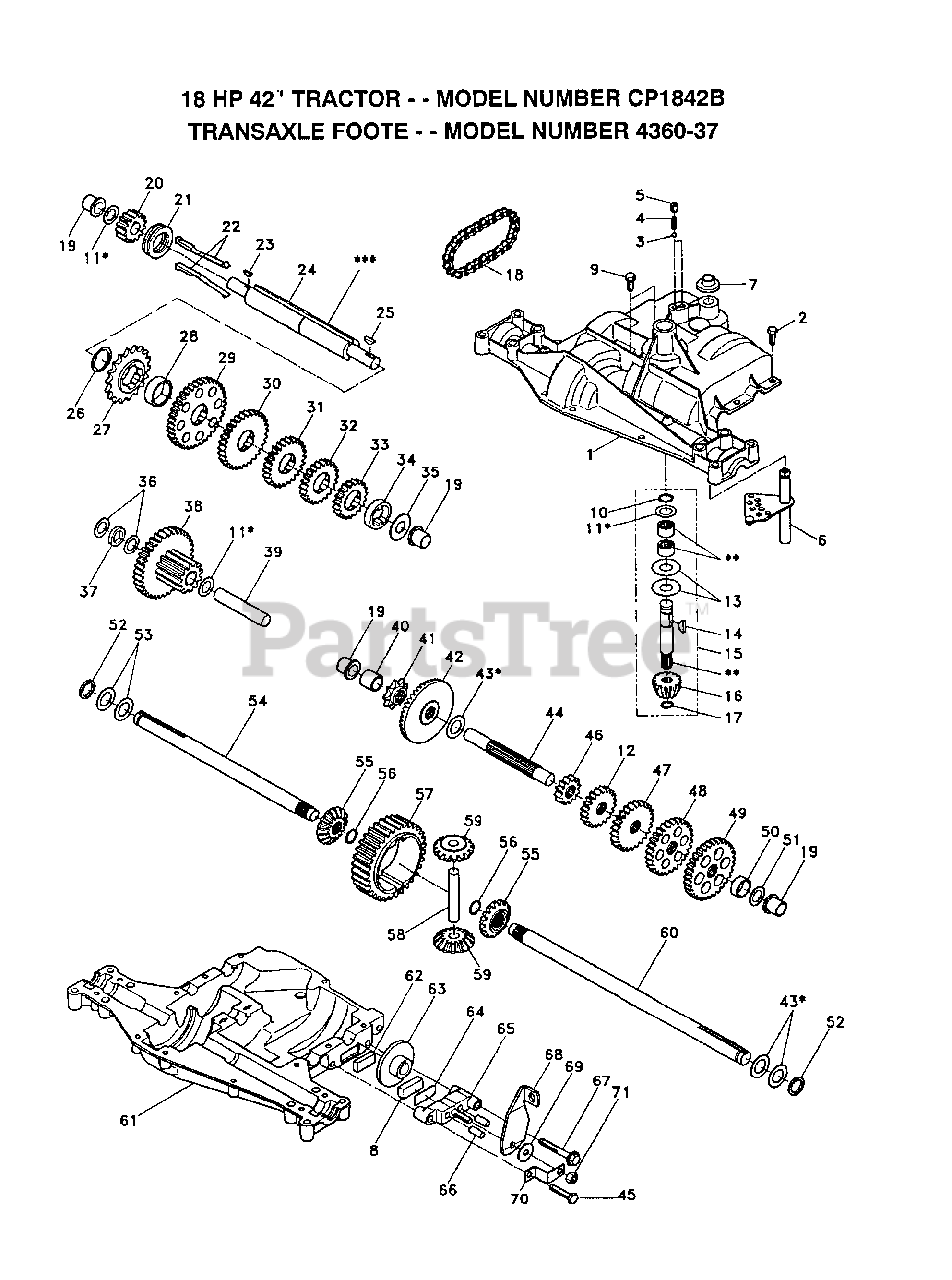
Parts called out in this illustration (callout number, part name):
1	HOUSING UPPER
3	BALL, DETENT
4	SPRING, DETENT
5	SCREW, SET
6	KIT SHIFTER ASSY
7	BOOT, SHIFTER
8	PUCK, FRICTION
9	SCREW TAPPING WITH SEALER
10	RING RETAINING
11	ASSY, KIT, SHIM .625 SHAFT
12	GEAR SPUR, 15 TEETH
13	WASHER, PLAIN .632 X 1.38 X .046
14	KEY WOODRUFF #9
15	ASSY KIT INPUT SHAFT
16	PINION BEVEL 14 TEETH
17	RING, RETAINING
18	CHAIN, 24 PITCHES
19	BEARING, FLANGE
20	GEAR SPUR, 14 TEETH
21	COLLAR CLUTCH
22	KEY CLUTCH
23	KEY WOODRUFF #3
24	SHAFT INTERMEDIATE
25	KEY, WOODRUFF, #61
26	RING, RETAINING
27	SPROCKET, 18 TEETH
29	GEAR, SPUR, 37 TEETH
30	GEAR, SPUR, 35 TEETH
31	GEAR, SPUR, 30 TEETH
32	GEAR, SPUR, 25 TEETH
33	GEAR, SPUR, 22 TEETH
34	GEAR, SPUR, 19 TEETH
35	WASHER, PLAIN .640 X 1.37 X .061
36	WASHER, PLAIN .632 X 1.00 X .026
37	SPACER .630 X 1.00 X .169
38	ASSY GEAR COMB 12&35 TEETH
39	SHAFT, IDLER
40	SPACER .635 X .875 X .755
41	SPROCKET, 9 TEETH
42	GEAR, BEVEL, 42 TEETH
43	ASSY, KIT, SHIM .750 SHAFT
44	SHAFT, DRIVE
45	SCREW TAPPING
46	GEAR, SPUR, 12 TEETH
47	GEAR, SPUR, 20 TEETH
48	GEAR, SPUR, 25 TEETH
49	GEAR, SPUR, 28 TEETH
50	GEAR, SPUR, 31 TEETH
51	WASHER, PLAIN .632 X 1.00 X .060
52	WASHER, NEOPRENE
53	WASHER, PLAIN .758 X 1.25 X .031
54	AXLE LEFT HAND
55	GEAR MITER 15 TEETH
56	RING, RETAINING
57	GEAR, SPUR, 32 TEETH
58	SHAFT, CROSS
59	GEAR, MITER, 15 TEETH
60	AXLE, R.H.
61	HOUSING LOWER
62	PUCK, FRICTION
63	DISC, BRAKE
65	JAW, BRAKE
66	PIN, DOWEL
67	SCREW, SELF-TAPPING
68	LEVER, ACTUATING
69	WASHER, PLAIN .321 X 1.00 X .055
70	BRACKET, ANTI-ROTATION
71	LOCKNUT 5/16-24
